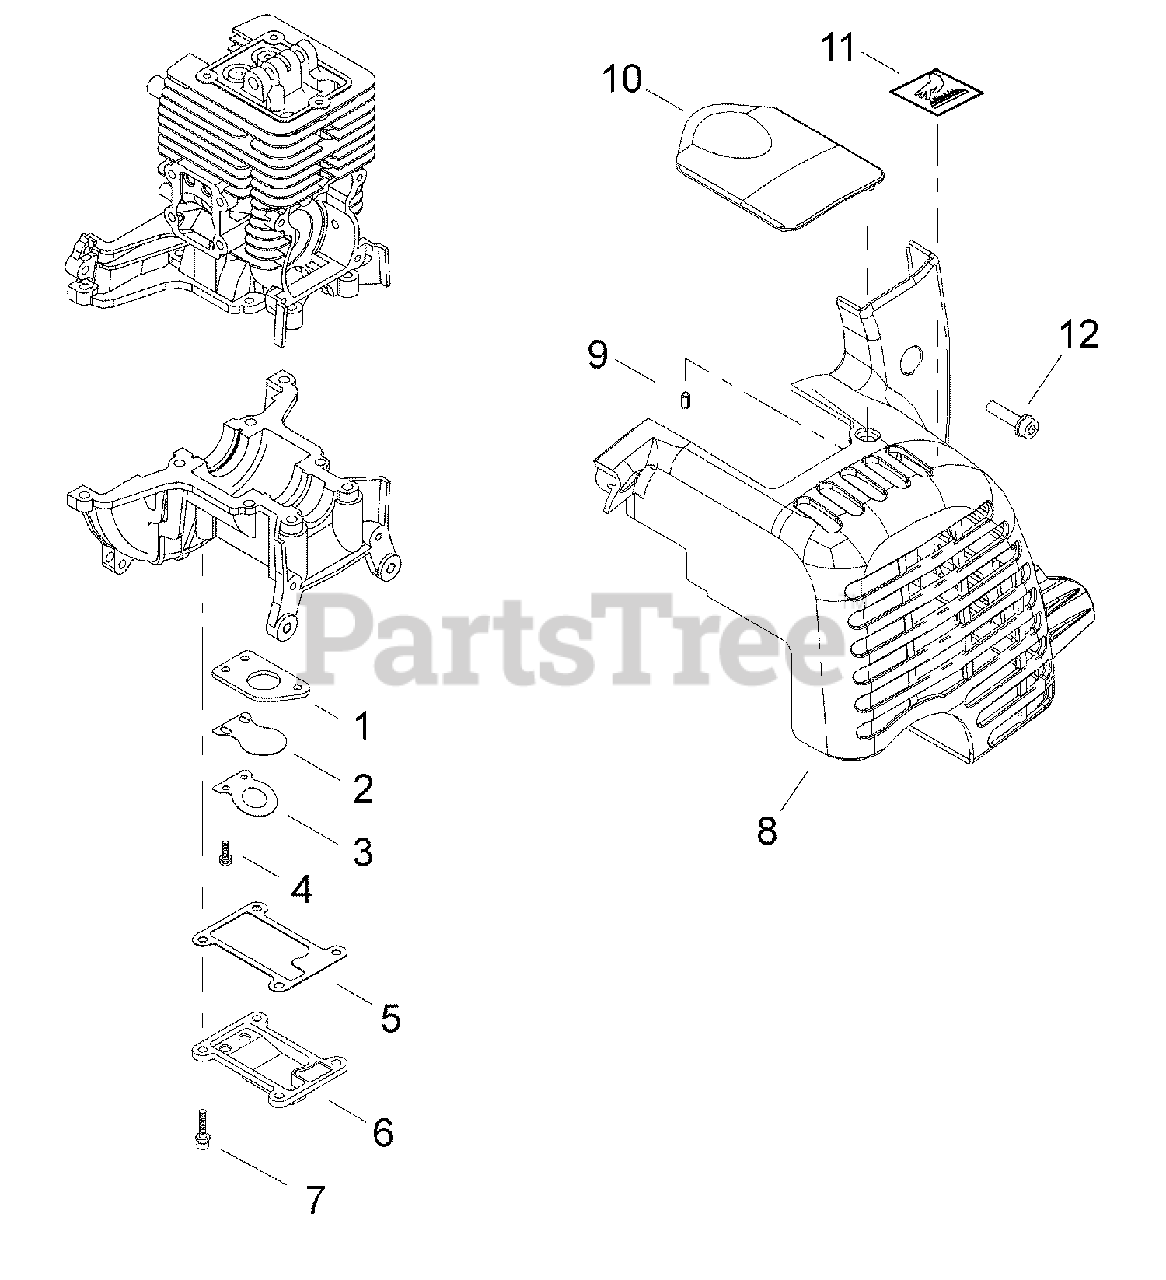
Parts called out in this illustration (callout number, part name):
1	PLATE, REED BACKING
2	VALVE, REED
3	STOP, REED VALVE
4	SCREW M3×10
5	GASKET, REED VALVE
6	COVER, REED VALVE
7	BOLT M4×14
8	COVER, ENGINE
9	PIN, SPRING 4×8
10	COVER, SPARK PLUG
11	LABEL, CAUTION - HOT
12	BOLT M5×20
